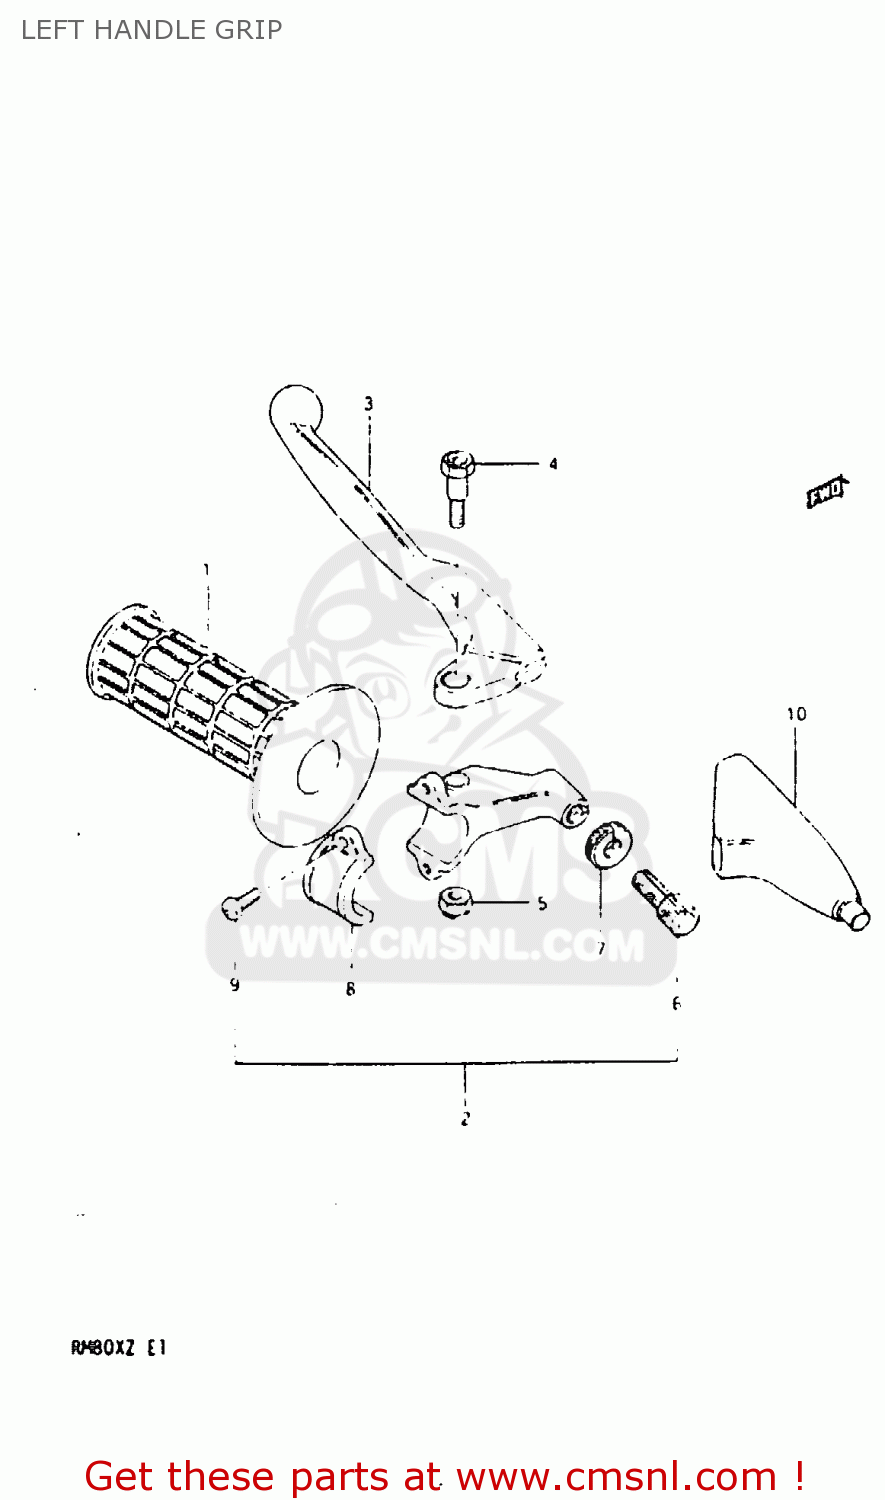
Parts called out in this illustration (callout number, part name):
1	GRIP,LEFT
2	LEVER ASSY,CLUTCH
3	LEVER,CLUTCH
4	BOLT,LEVER
5	NUT 6MM
6	ADJUSTER,CABLE
7	NUT,CABLE ADJUSTER
8	BRACKET,CLUTCH LEVER HOLDER
9	SCREW
10	COVER,CLUTCH LEVER
